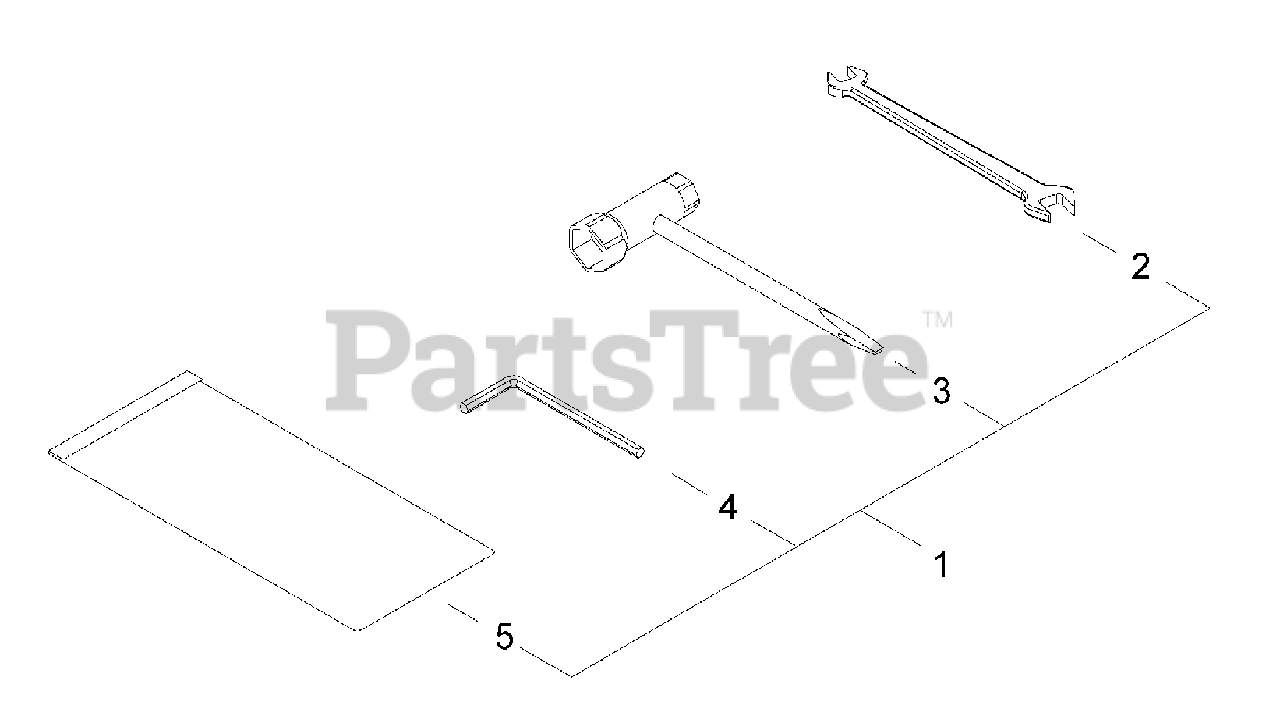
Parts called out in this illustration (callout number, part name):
1	TOOL KIT
2	SPANNER - 8X10mm
3	T-WRENCH - 13X16mm
4	HEX KEY - 4mm
5	BAG, TOOL
